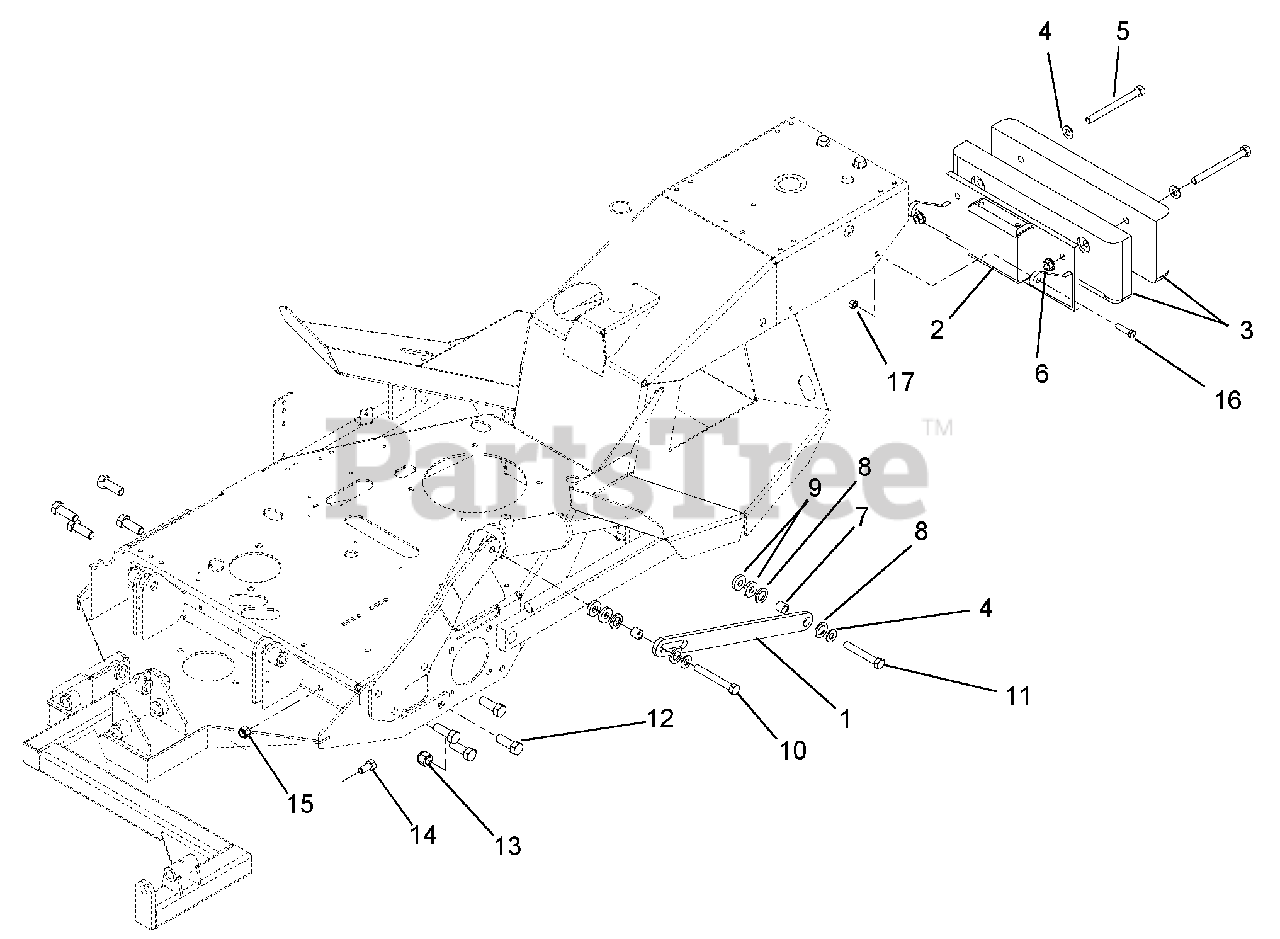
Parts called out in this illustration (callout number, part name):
1	LIMITER ARM
2	COUNTERWEIGHT MOUNT WELDMENT
3	WEIGHT, CAST IRON
4	FLATWASHER, 1/2
5	HHCS, 1/2-13 x 5-1/2
6	HEX NUT, 1/2-13 SERRATED FLANGE
8	WASHER, 3/4 SAE
9	WASHER, 1.25 X .531 X .25
10	HHCS, 1/2-13 X 4
11	HHCS, 1/2-13 X 3-1/2
12	HHCS, 5/8-11 X 1-3/4
13	HEX NUT, 5/8-11 NYLOCK
14	HHCS 1/2-13 X 1 G5 ZP
15	NYLOCK NUT 1/2-13
16	HHCS 3/8-16 X 1-1/2"
17	NYLOCK NUT 3/8-1
